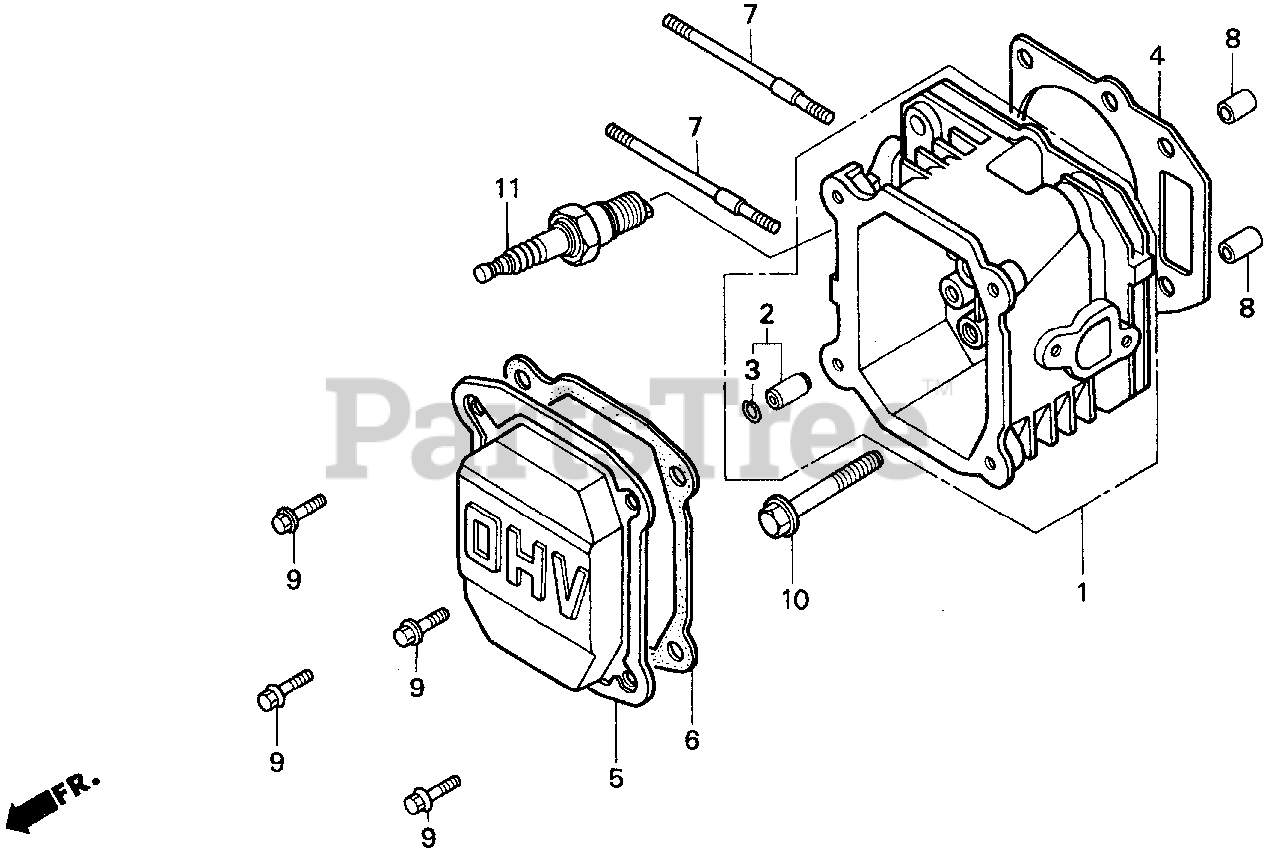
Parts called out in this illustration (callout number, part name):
1	CYLINDER HEAD (USA)
2	GUIDE, EX. VALVE (OS)
3	CLIP, VALVE GUIDE
4	GASKET, CYLINDER HEAD
5	COVER, HEAD
6	GASKET, HEAD COVER
7	BOLT, STUD (6X83)
8	PIN A, DOWEL (10X16)
9	BOLT, FLANGE (6X14)
9	BOLT, FLANGE (6X16)
10	BOLT, FLANGE (8X50)
11	SPARK PLUG (BPR4ES) (NGK)
11	SPARK PLUG (BPR5ES) (NGK)
11	SPARK PLUG (BPR6ES) (NGK)
